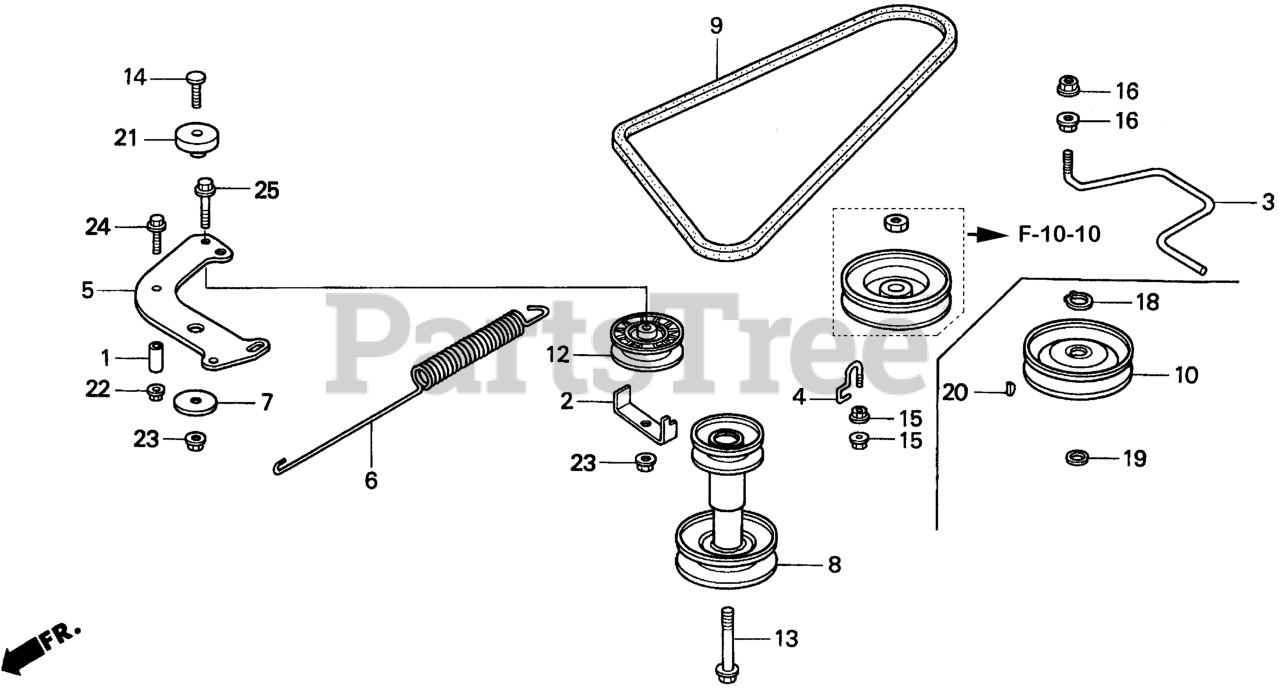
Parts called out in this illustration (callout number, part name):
1	COLLAR, AIR CLEANER Use from Engine SN 1786085.
2	STOPPER A, BELT
3	STOPPER B, BELT
4	STOPPER C, BELT
5	ARM, TENSIONER
6	SPRING, BELT TENSIONER
7	WASHER (42X8.5)
8	PULLEY, ENGINE
9	V-BELT, PRIMARY
10	PULLEY ASSY., TRANSMISSION
12	ROLLER, TENSION
13	BOLT, FLANGE (7/16")
14	BOLT, SPECIAL (8X37)
15	NUT, FLANGE (6MM)
16	NUT, FLANGE (8MM)
18	CIRCLIP, EX. (5/8")
19	RING, RETAINING
20	KEY, WOODRUFF (#9)
21	COLLAR, TENSION ARM
22	NUT, FLANGE (6MM)
23	NUT, FLANGE (8MM)
24	BOLT, FLANGE (6X35)
25	BOLT, FLANGE (8X40)
